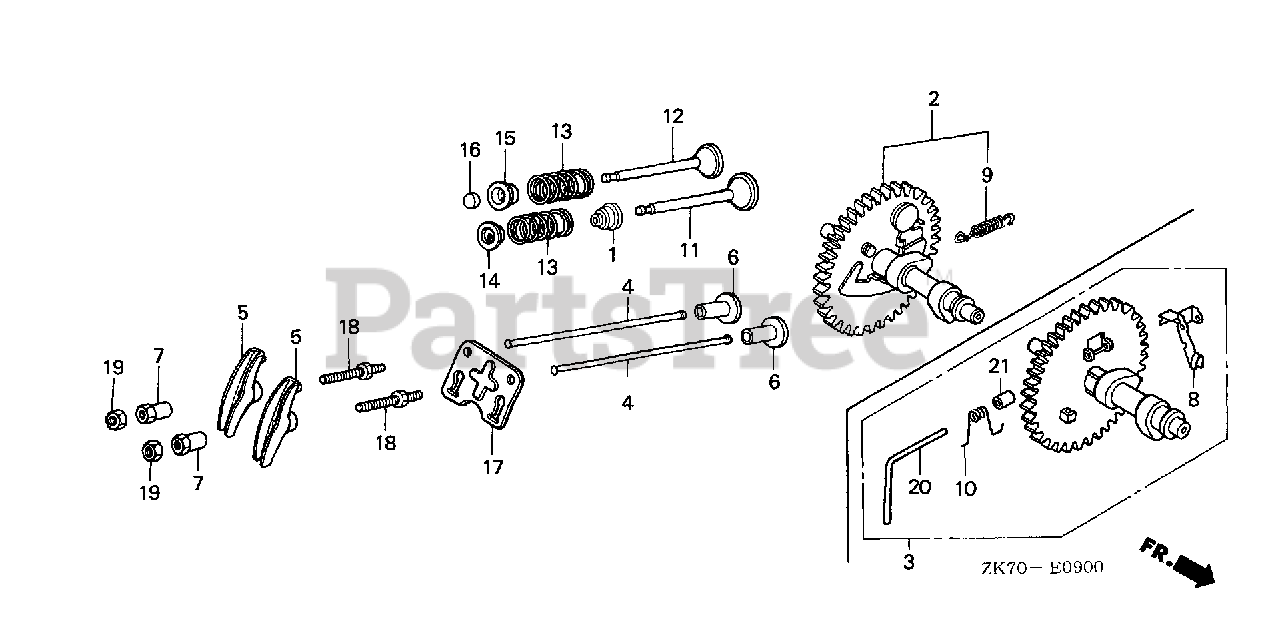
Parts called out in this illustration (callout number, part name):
1	SEAL, VALVE STEM
2	CAMSHAFT ASSY.
5	ARM, VALVE ROCKER
6	LIFTER, VALVE
7	PIVOT, ROCKER ARM
9	SPRING, WEIGHT RETURN
11	VALVE, IN.
12	VALVE, EX.
13	SPRING, VALVE
14	RETAINER, IN. VALVE SPRING
14	RETAINER, VALVE SPRING
15	RETAINER, EX. VALVE SPRING
16	ROTATOR, VALVE
17	PLATE, PUSH ROD GUIDE
18	BOLT, PIVOT (8MM)
19	NUT, PIVOT ADJUSTING
